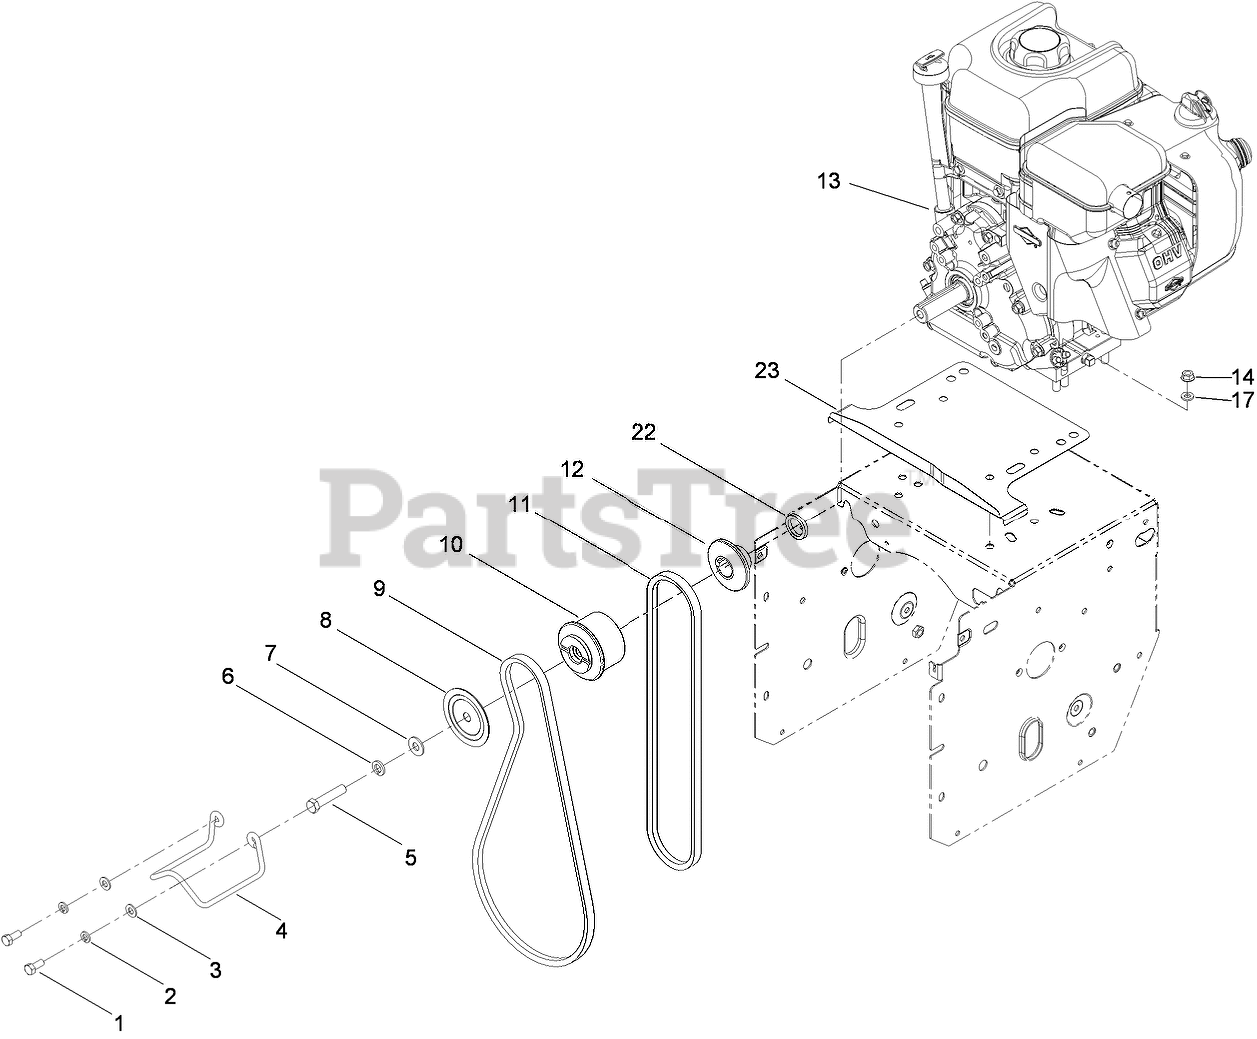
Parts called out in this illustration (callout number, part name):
1	SCREW-HH
2	WASHER-LOCK
3	WASHER-PLAIN
4	GUIDE-BELT
5	SCREW-HH
6	WASHER-LOCK
7	WASHER-FLAT
8	SHEAVE-HALF, IMPELLER
9	BELT-V
10	PULLEY-ENGINE, CENTER
11	V BELT-TRACTION
12	SHEAVE-HALF, TRACTION
14	NUT-HF
17	WASHER-FLAT
22	SPACER-HARDENED
23	SHIELD-DRIVE
